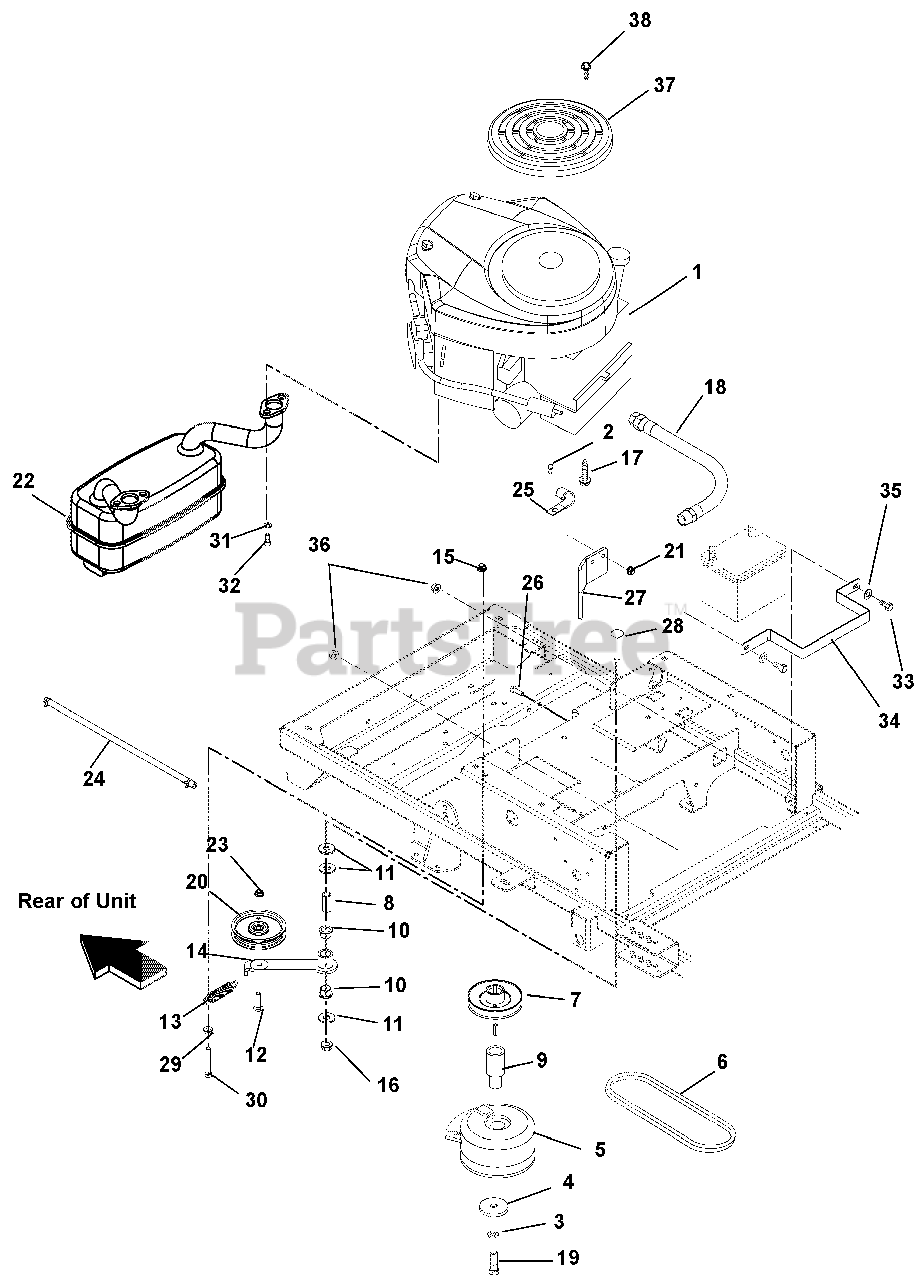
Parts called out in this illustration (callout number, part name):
1	ENGINE, 20HP COURAGE TWIN
1	ENGINE, COURAGE 25HP
1	ENGINE, 18HP V-TWIN CE
2	@SCR-TAP .25-20X.37 HWH YWZ TR
3	@WSHR-LK .44X.109 REG YWZC
4	WSHR-FL-STL .469X2.00X.25 YWZC
5	CLUTCH, MS
5	CLUTCH, MS WITH BRAKE
6	V-BELT, HA-WRAPPED
7	PLY-V 4.5X1.5 AB SECTION W/KEY
8	BSHG-SLV .500X.750X1.560
9	EXT-CRANKSHAFT LOWER
10	BSHG-FLG 0.75X0.875X.625X1.125
11	@WSHR-FL-STL.563X1.38X.109YWZC
12	@BLT-RDHDSQNK .38-16X1.50 G5YZ
13	SG-TENS .105X.812X3.88 WLD 15
14	WMT, GROUND DRIVE IDLER ARM
15	@NUT-LK-NYL-FLG .38-16 YWZC
16	@NUT-LK-TOP-FLG .50-13 YWZC
17	@SCR-TAP .38-16X1.00 HWH TR YZ
18	HOSE, HYD .38-11-0K M6N0-F6J0
19	BLT-HEX .44-20X4.50 GR8 YWZC
20	ASM, 4" IDLER (.75 WIDE)
21	@NUT-LK-NYL-FLG .31-18 YWZC
22	MUFFLER
22	MUFFLER - TWIN BRIGGS
23	@NUT-LK-TOP-FLG .38-16 YWZC
24	ASM, FUEL HOSE
25	J-CLAMP
26	@BLT-HEX .31-18X1.00 GR5 YWZC
27	CLUTCH STOP
28	@BLT-RDHDSQNK .50-13X2.50 G5YZ
29	@NUT-SPNLK-FLG .375-16 YWZC
30	@BLT-HEX .38-16X2.50 GR5 YWZC
31	@WSHR-LK .31X.078 REG YWZC
32	SCR-CAP .31-18X.75 S/HD
33	@BLT-HEX .25-20X.75 GR5 YWZC
34	BRKT, BATTERY HOLD DOWN
35	@WSHR-FL-STL.281X.62X.065 YWZC
36	NUT-KEPS .250-20
37	GUARD, BRIGGS ENGINE
38	SCREW, 8-16X.87 PHPAN 3 LOBE
